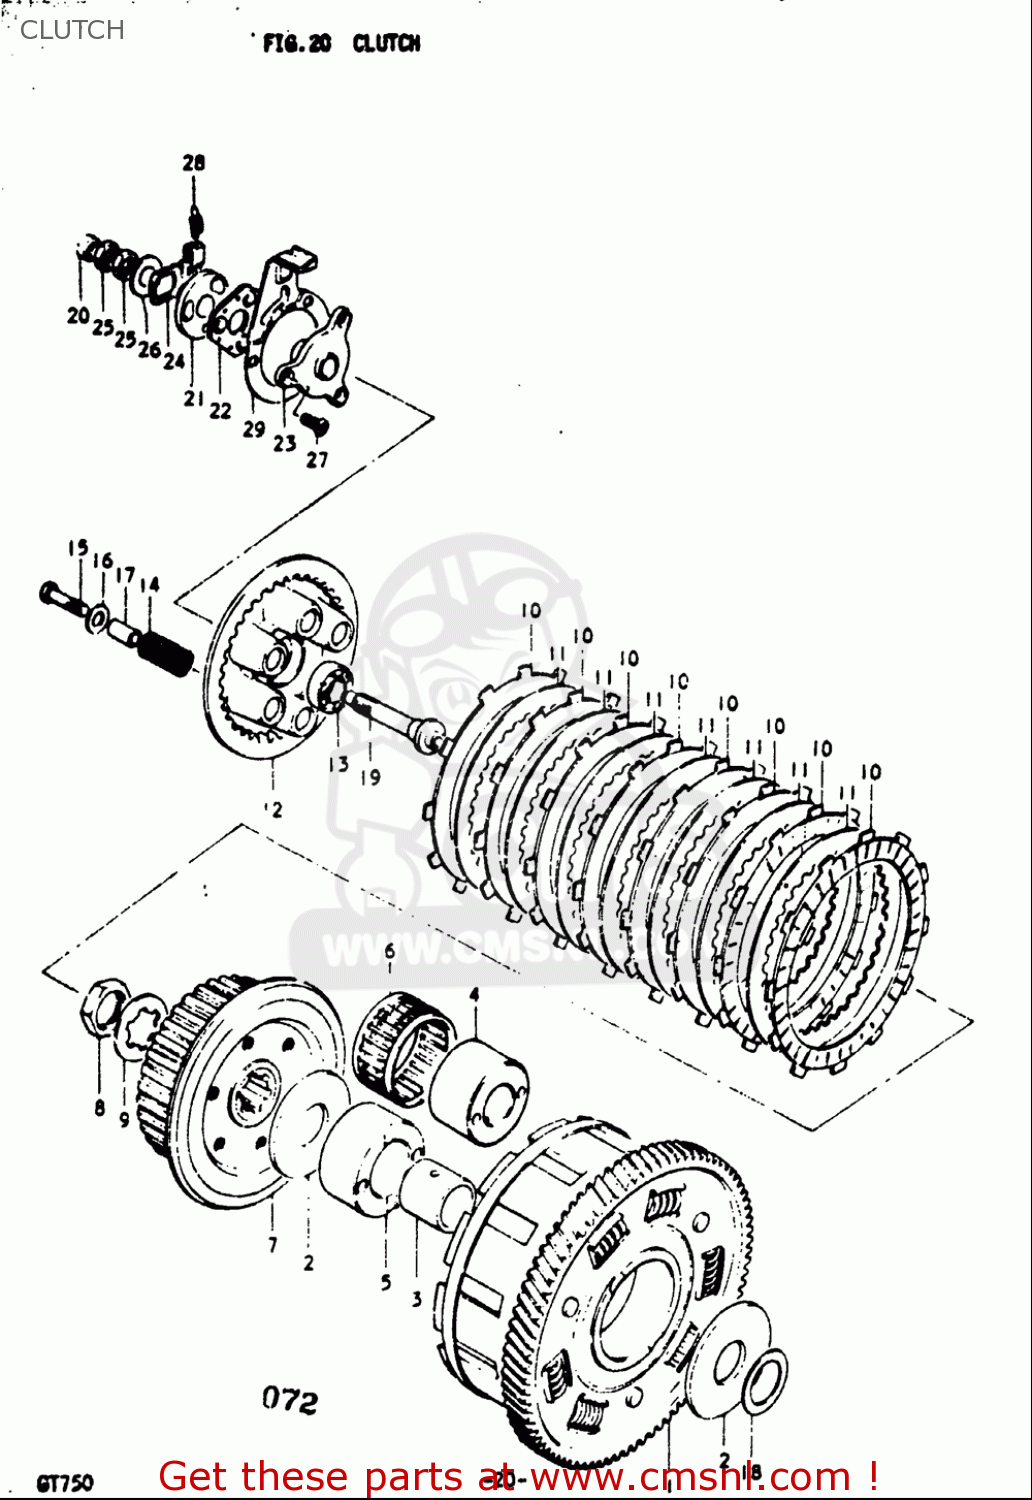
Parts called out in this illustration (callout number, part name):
2	WASHER
4	SPACER
5	SPACER
6	BEARING(51X56X28)
8	NUT
9	WASHER,LOCK
10	PLATE,CLUTCH DRIVE (NAS)
11	PLATE,CLUTCH DRIVEN(T:2.0) (NAS)
14	SPRING
15	BOLT
16	WASHER
18	SHIM(25X36X0.5)
20	OIL SEAL (10X17X5.5)
22	BALL,CLUTCH RELEASE
24	ARM,CLUTCH RELEASE
25	NUT
27	SCREW
28	SPRING
